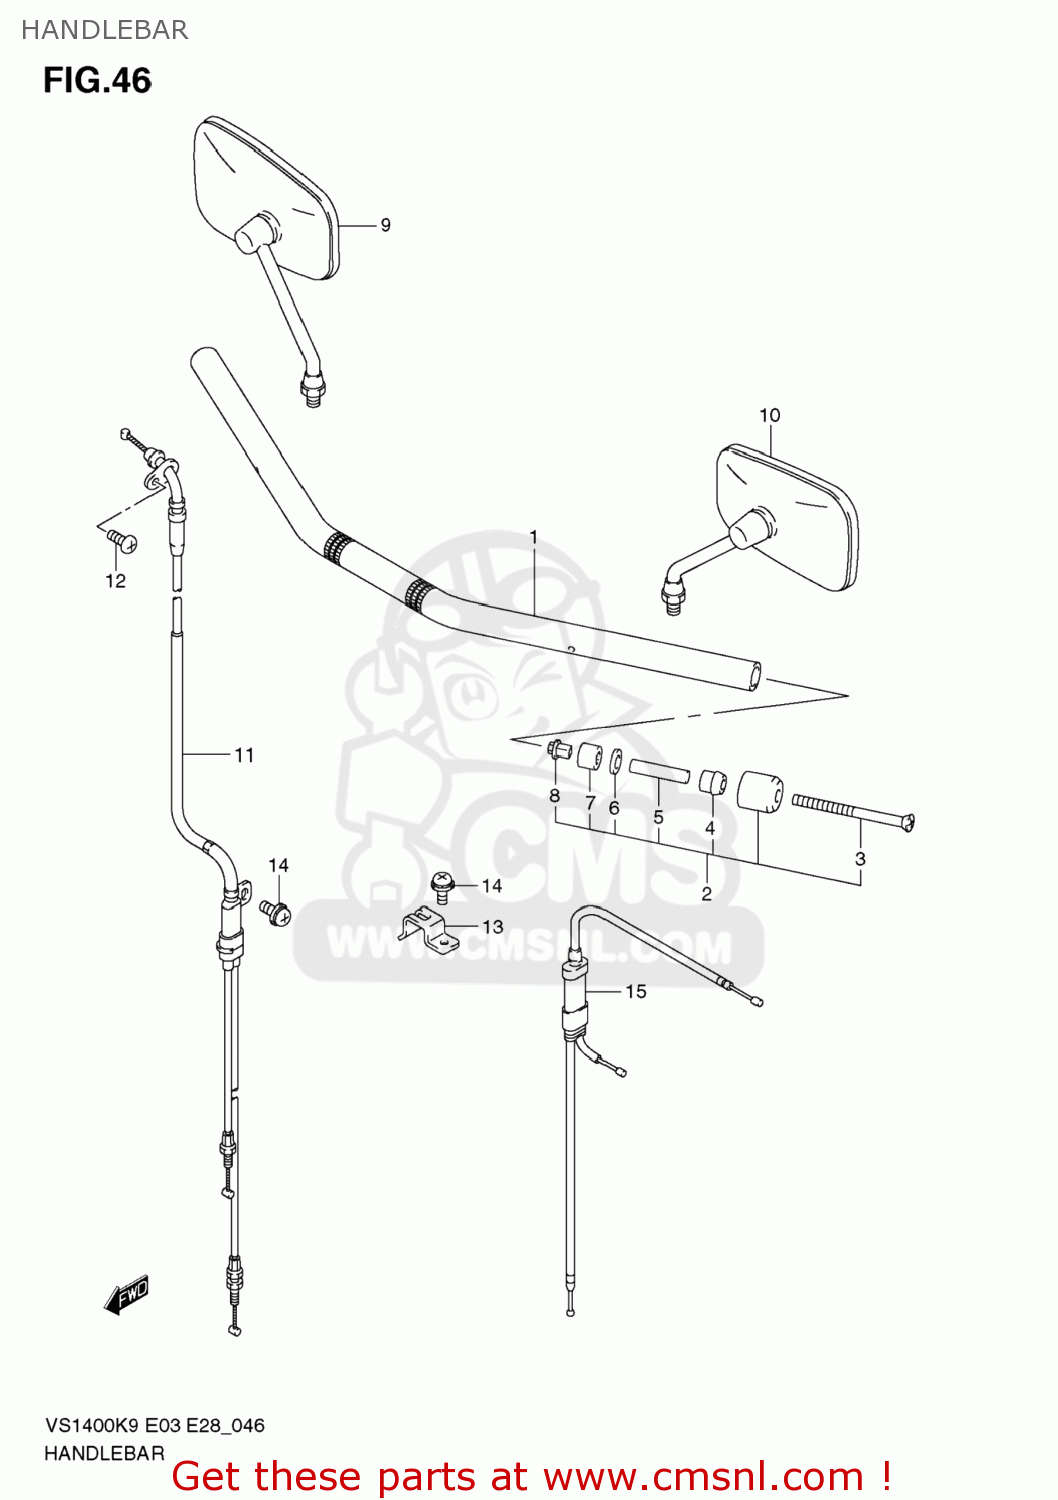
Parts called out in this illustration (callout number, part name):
1	HANDLEBAR
2	BALANCER SET,HANDLEBAR
3	SCREW(6X127)
4	EXPANDER,HANDLE BALANCER NO.2
5	SPACER,EXPANDER
6	WASHER(6.5X16X4)
7	EXPANDER,HANDLE BALANCER
8	NUT,HANDLE BALANCER
9	MIRROR ASSY,RR VIEW,R
10	MIRROR ASSY,RR VIEW,L
11	CABLE ASSY,THROTTLE
12	SCREW(5X10)
13	CLAMP,THROTTLE CABLE CONNECTOR
14	SCREW
15	CABLE ASSY,STARTER
